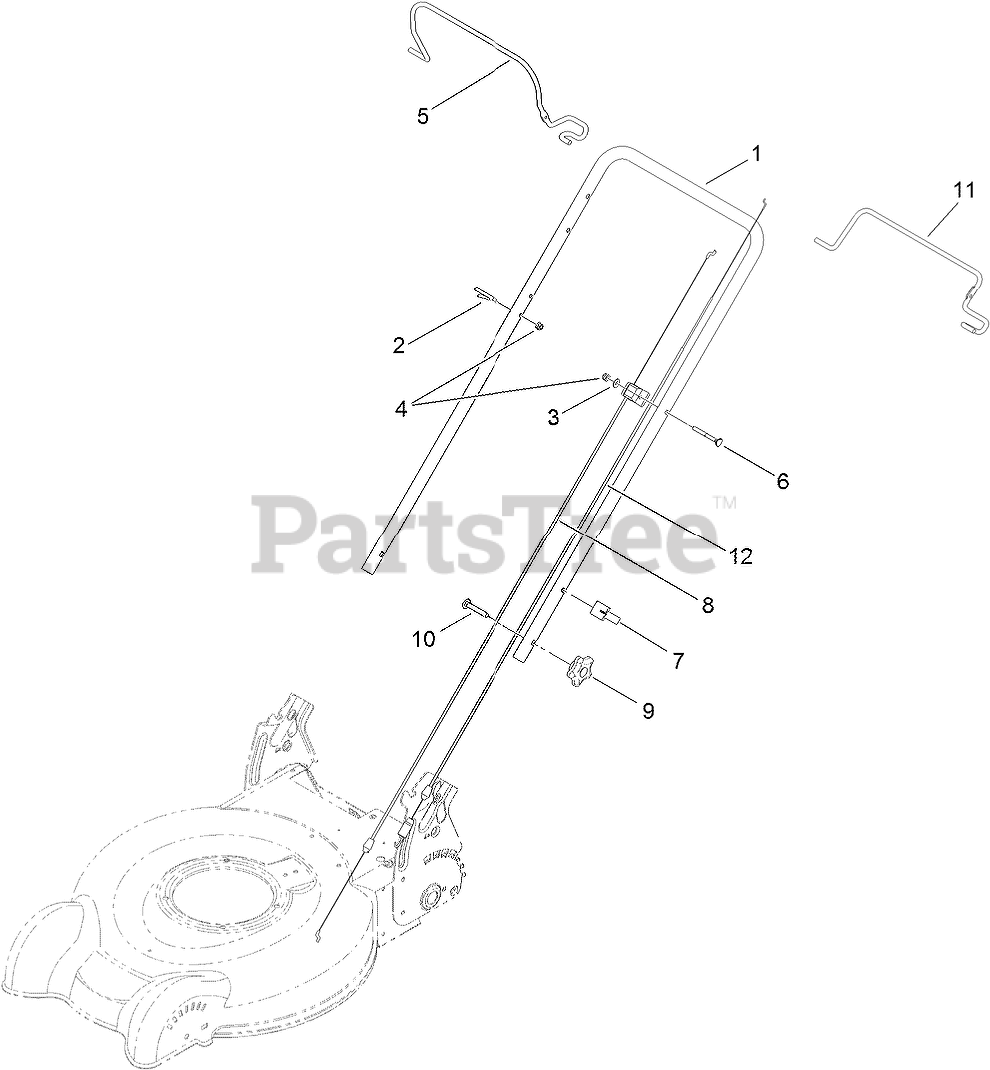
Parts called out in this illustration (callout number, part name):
1	HANDLE-UPPER
2	GUIDE-ROPE
3	WASHER-FLAT
4	NUT-LOCK, NI
5	BAIL-BRAKE
6	SCREW-HANDLE
7	GUIDE-CABLE
8	CABLE-BRAKE
9	KNOB-HANDLE
10	Screw-CARR
11	BAIL-TRACTION, 2-BAIL FLAT
12	CABLE-TRACTION
